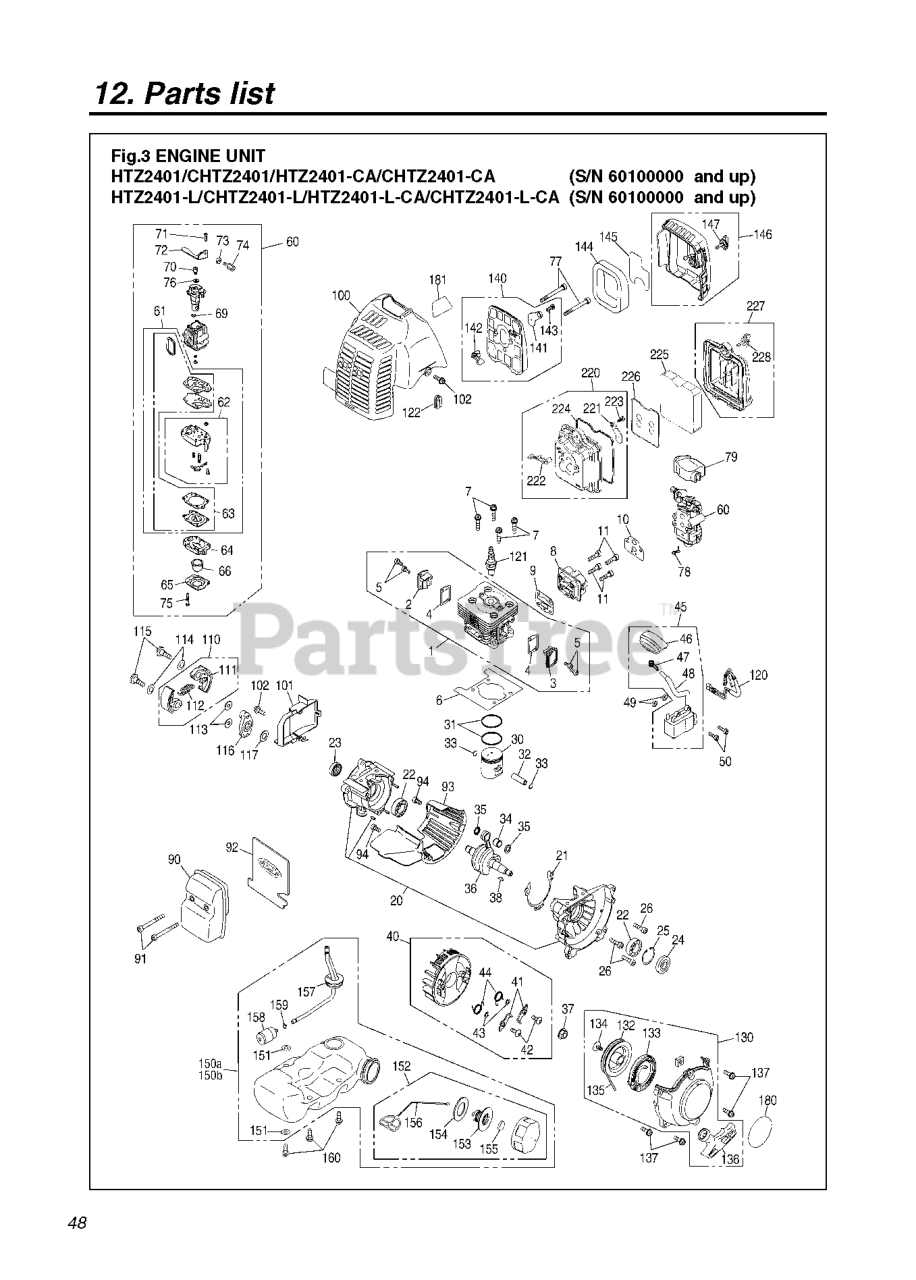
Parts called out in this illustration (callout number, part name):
1	CYLINDER COMPLETE
2	COVER, TR-S
3	COVER, TR-F
4	GASKET, TR
5	BOLT
6	GASKET, BASE
7	BOLT
8	INSULATOR
9	INSULATOR GASKET(R-848F0814B0)
10	GASKET, CARB
11	BOLT TORX
20	CRANKCASE COMP
21	GASKET, CASE
24	SEAL
32	PIN
36	CRANKSHAFT COMP
37	NUT
38	KEY
40	ROTOR ASSY
43	WASHER 5X10X10
45	COIL ASSY
46	CAP
49	SPACER
60	CARBURETOR ASSY.
61	REBUILD KIT
62	CARBURETOR BODY
63	GASKET KIT
65	1OVER
69	RING
70	SWIVEL
71	SCREW
72	BRACKET
73	NUT
74	ADJUSTER
76	WASHER
78	CLIP
100	COVER,ENGINE
101	DEFLECTOR
110	SHOE COMP
116	PLATE CLUTCH
120	CORD COMP
121	PLUG CMR7H
130	RECOIL-A
134	SCREW
140	BODY ASSY
141	PLATE CHOKE
143	SCREW
146	COVER ASSEMBLY
152	CAP A
153	HOLDER-A
157	PIPE COMP
158	FILTER ASSY
159	CLIP
180	LABEL RECOIL
181	LABEL COVER
220	BODY-A (RPLS 848F028310)
221	PLATE.CHOKE
222	LEVER CHOKE
223	SCREW
224	PACKING
225	ELEMENT
226	PLATE
227	COVER A (RPLS T151382200)
228	KNOB
